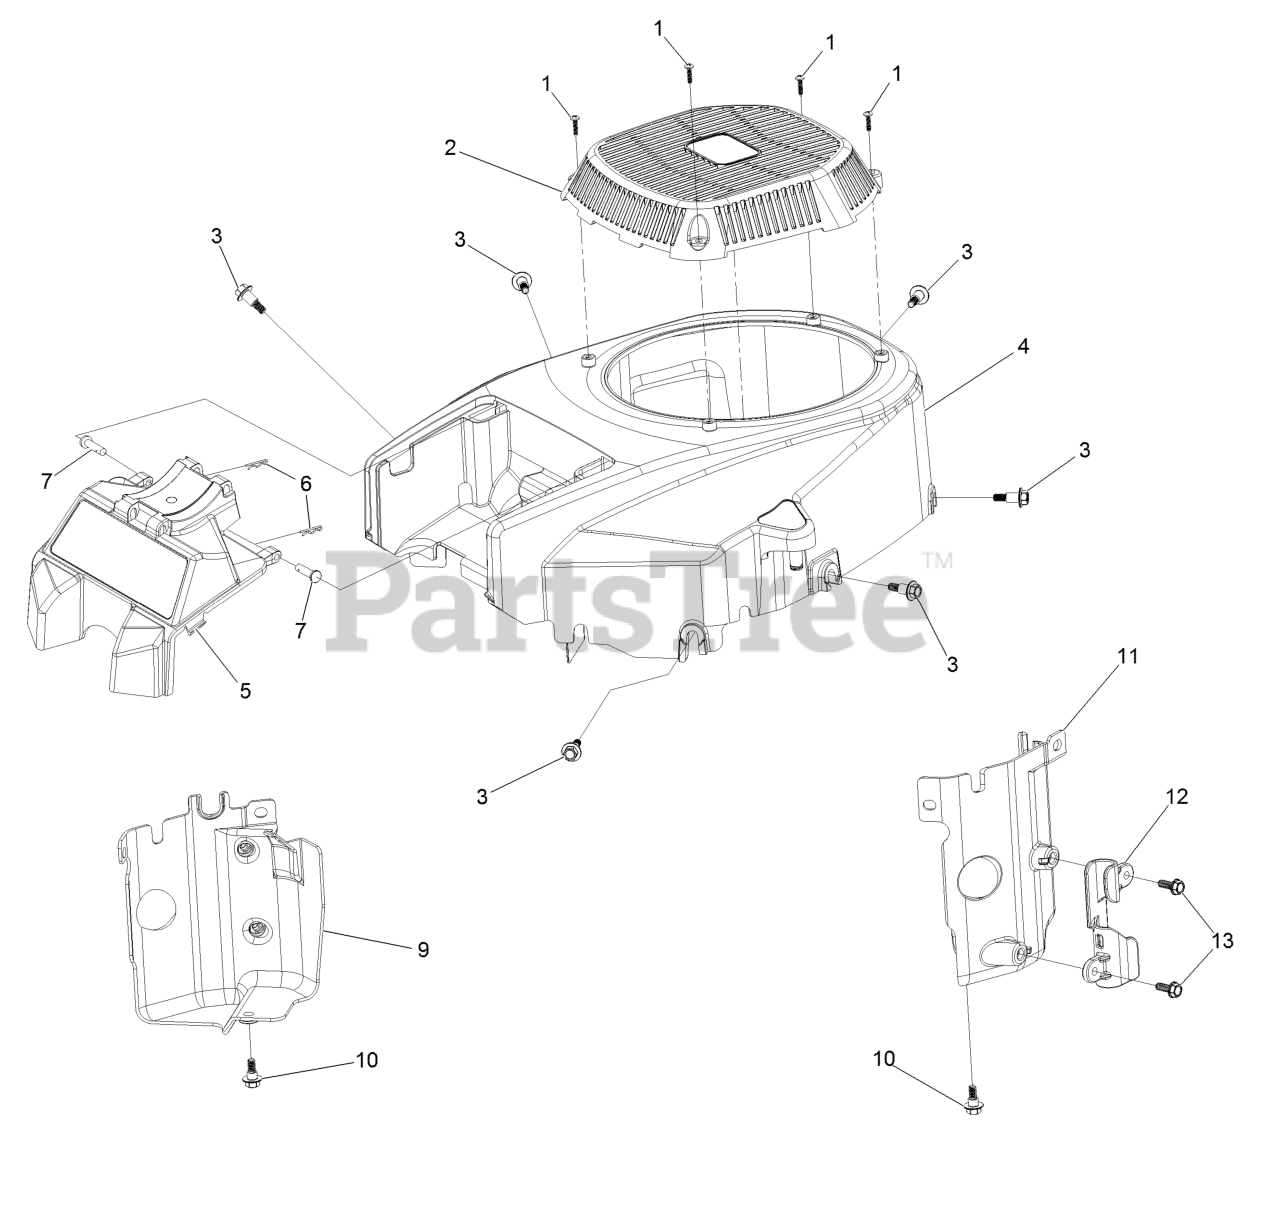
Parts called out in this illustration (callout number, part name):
1	Screw-PPH, Plastic
2	Cover-Fan
3	Screw-Shoulder, HWH
4	Shroud-Engine
5	Support-Filter
6	Pin-Hair
9	Baffle-Air, Left
10	Screw-Shoulder, HHF
11	Baffle-Air, Right
12	Cleat-Hose
13	Screw-HHF
